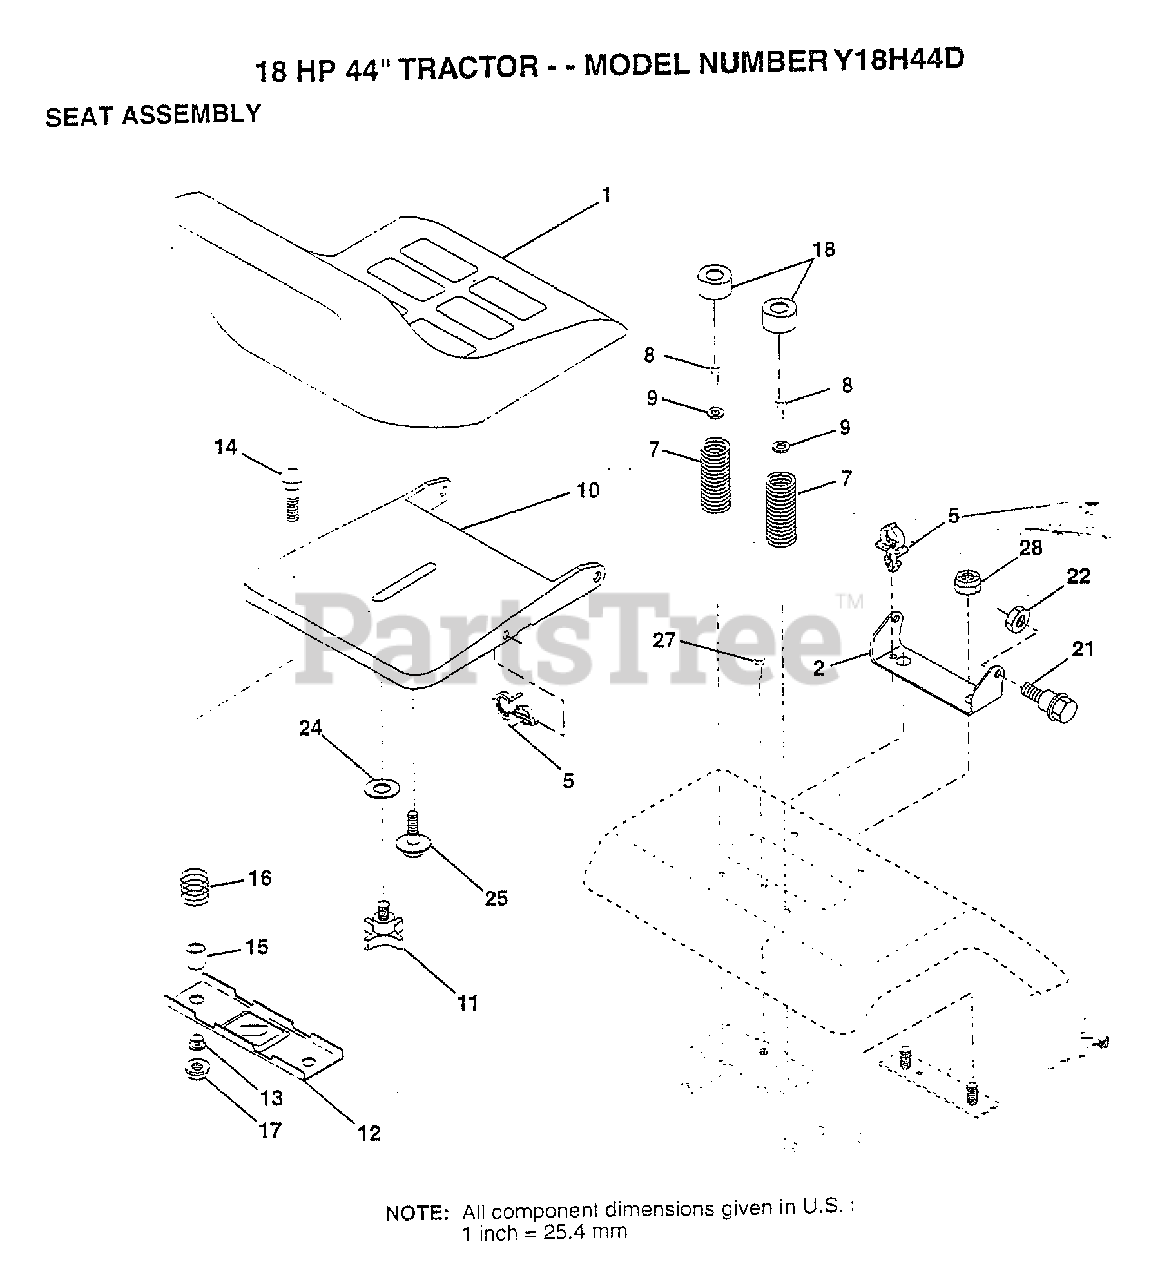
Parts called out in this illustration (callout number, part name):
2	BRACKET PVT SEAT
5	CLIP.PUSH-IN.HING
7	SPRING COMPRESSIO
8	SCREW LT
9	WASHER
11	"KNOB 1/2"" YT"
12	BRKT SWITCH
13	BUSHING
15	SPACER SPLIT
16	SPRING COMPRESSED
18	CAP SPRING
21	BOLT.SHLD.5/16-18
24	WASHER
25	"BOLT,SHOULDER"
27	SCREW LT
